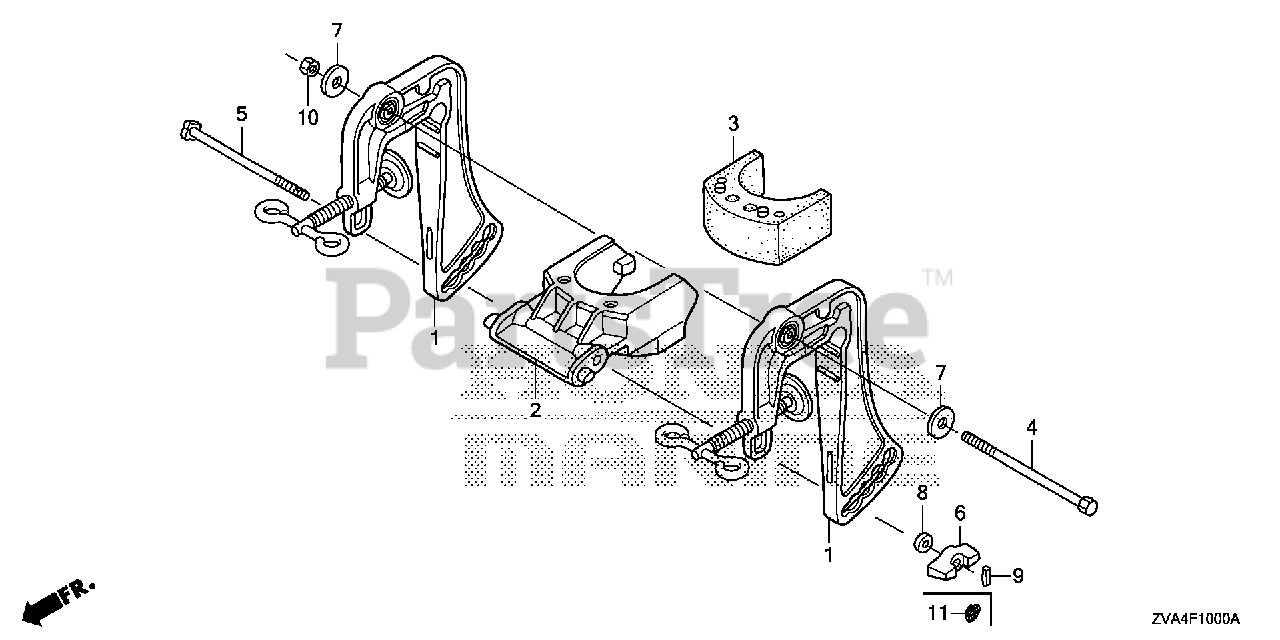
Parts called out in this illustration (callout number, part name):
1	BRACKET, STERN *NH246* (LOOSY GRAY)
2	RECEIVER, THRUST
3	RUBBER, THRUST
4	BOLT, HEX. (8X110)
4	BOLT, HEX. (8X114)
5	BOLT, DIAMOND (6X110)
6	WINGNUT
7	WASHER, PLAIN (8MM)
8	WASHER, PLAIN (6MM)
9	PIN, SPRING (2.5X8)
10	NUT, SELF-LOCK (8MM)
10	NUT, HEX. (8MM)
11	RING, STOPPER
